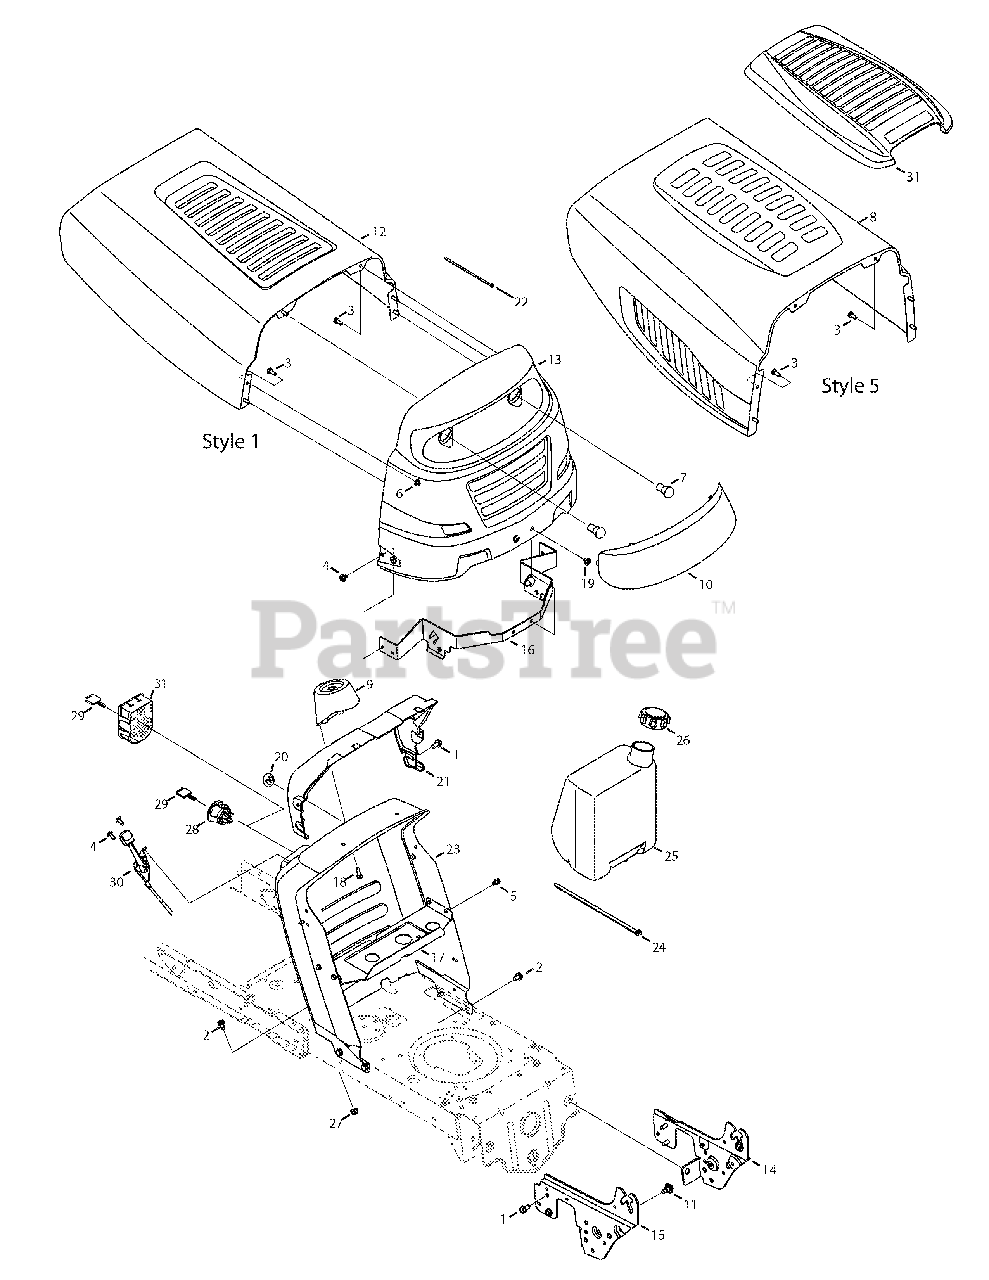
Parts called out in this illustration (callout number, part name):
1	S-Tapp Scr 5/16-18 x .75
2	Hex Wash HD TT Scr 5/16-12 x .625
3	Hex Bolt 1/4-20 x .62 Gr. 5
4	Hex Wash Hd Scr. 1/4-20 x .500
5	Hex Wash S-Tapp Scr 1/4-20 x .50
6	Hex L-Flg.Nut 1/4-20 Gr. F, Nylon
7	Miniature Lamp 12V Socket Type
9	Steering Support
11	Shoulder Screw .43 x .29, 5/16-18
18	Hex Tapp Scr 1/4 x .75" Lg.
19	S-Tapp Scr 5/16-18 x .375
22	Cable Tie
25	Fuel Tamk 1.5 gal.
26	Cap-Fuel
27	Hex L-Flg.Nut 5/16-18 Gr. F, Nylon
28	Switch (w/o RMC) 3 Position
28	Ignition Switch (w/ RMC)
29	Ignition Key w/o Plastic Cover
30	Choke/Throttle Cable 25"
31	Hood Cover - Style 5
31	Wire Harness (w/o RMC) 3 Position
31	Wire Harness (w/RMC, w/o AMM)
31	Wire Harness (w/RMC, w AMM)
31	Headlight Lens Reflector
